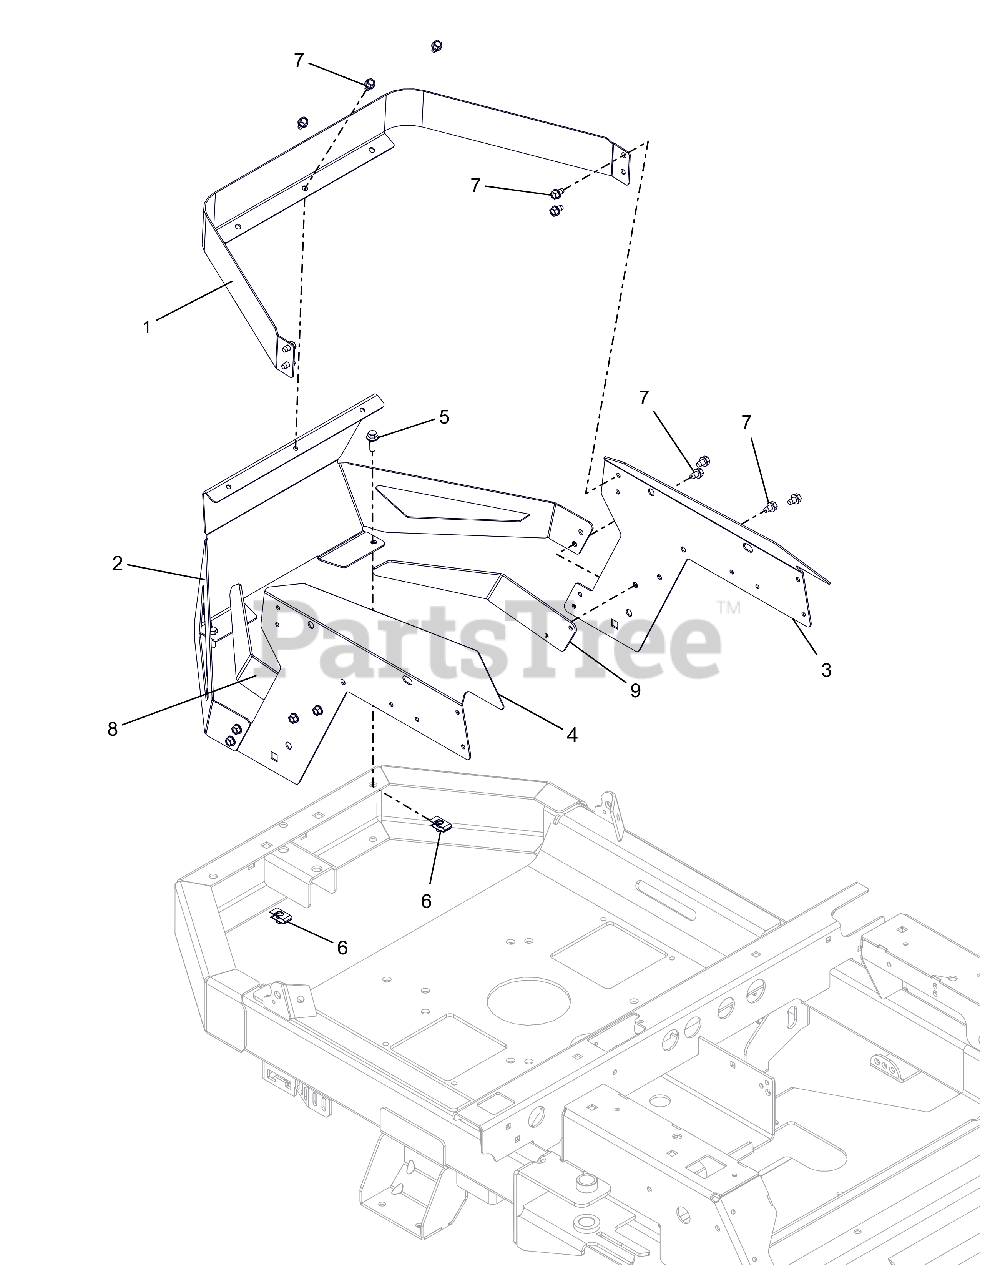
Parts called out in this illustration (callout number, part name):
1	GUARD, ENGINE -TOP TRIM
2	GUARD, ENGINE-BOTTOM BLACK
3	PANEL, LEFT REAR RENDER MOUNT
4	PANEL, RIGHT REAR FENDER MOUNT
5	BLT,HEX-FLG .25-20X.75 G5 BFP
6	NUT-RTNR .25-20X.56
7	SCR,TAP .25-20X.375 HWH TR ZCC
8	SHIELD, RH, ENGINE GUARD VALVE
9	SHIELD, LH, ENGINE GUARD VALVE
